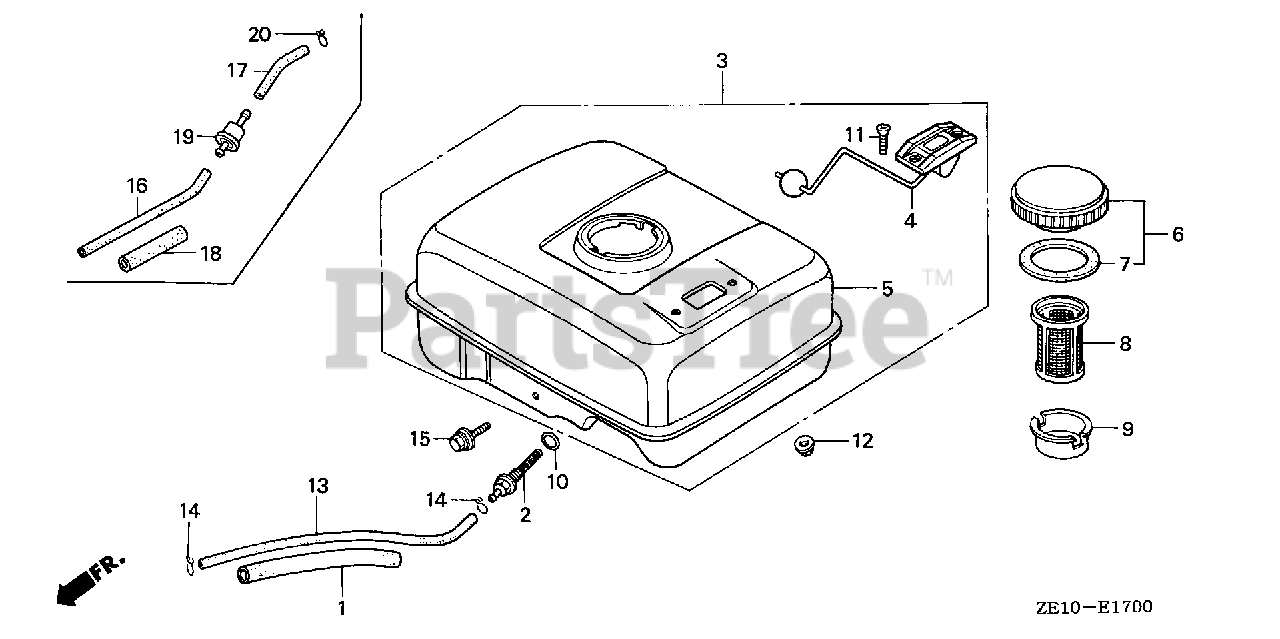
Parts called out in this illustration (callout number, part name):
1	RUBBER, SUPPORTER (107MM)
2	JOINT, FUEL TANK
5	TANK, FUEL *NH31* (MCKINLEY WHITE)
6	CAP, FUEL FILLER (BLACK)
7	GASKET, FUEL FILLER CAP (39X58X3)
10	O-RING (14MM) (ARAI)
10	O-RING (14MM) (NOK)
12	NUT, FLANGE (6MM)
13	BULK HOSE, FUEL (4.5X3000) (4.5X140)
14	CLIP, TUBE (B8)
15	BOLT, FLANGE (6X25)
